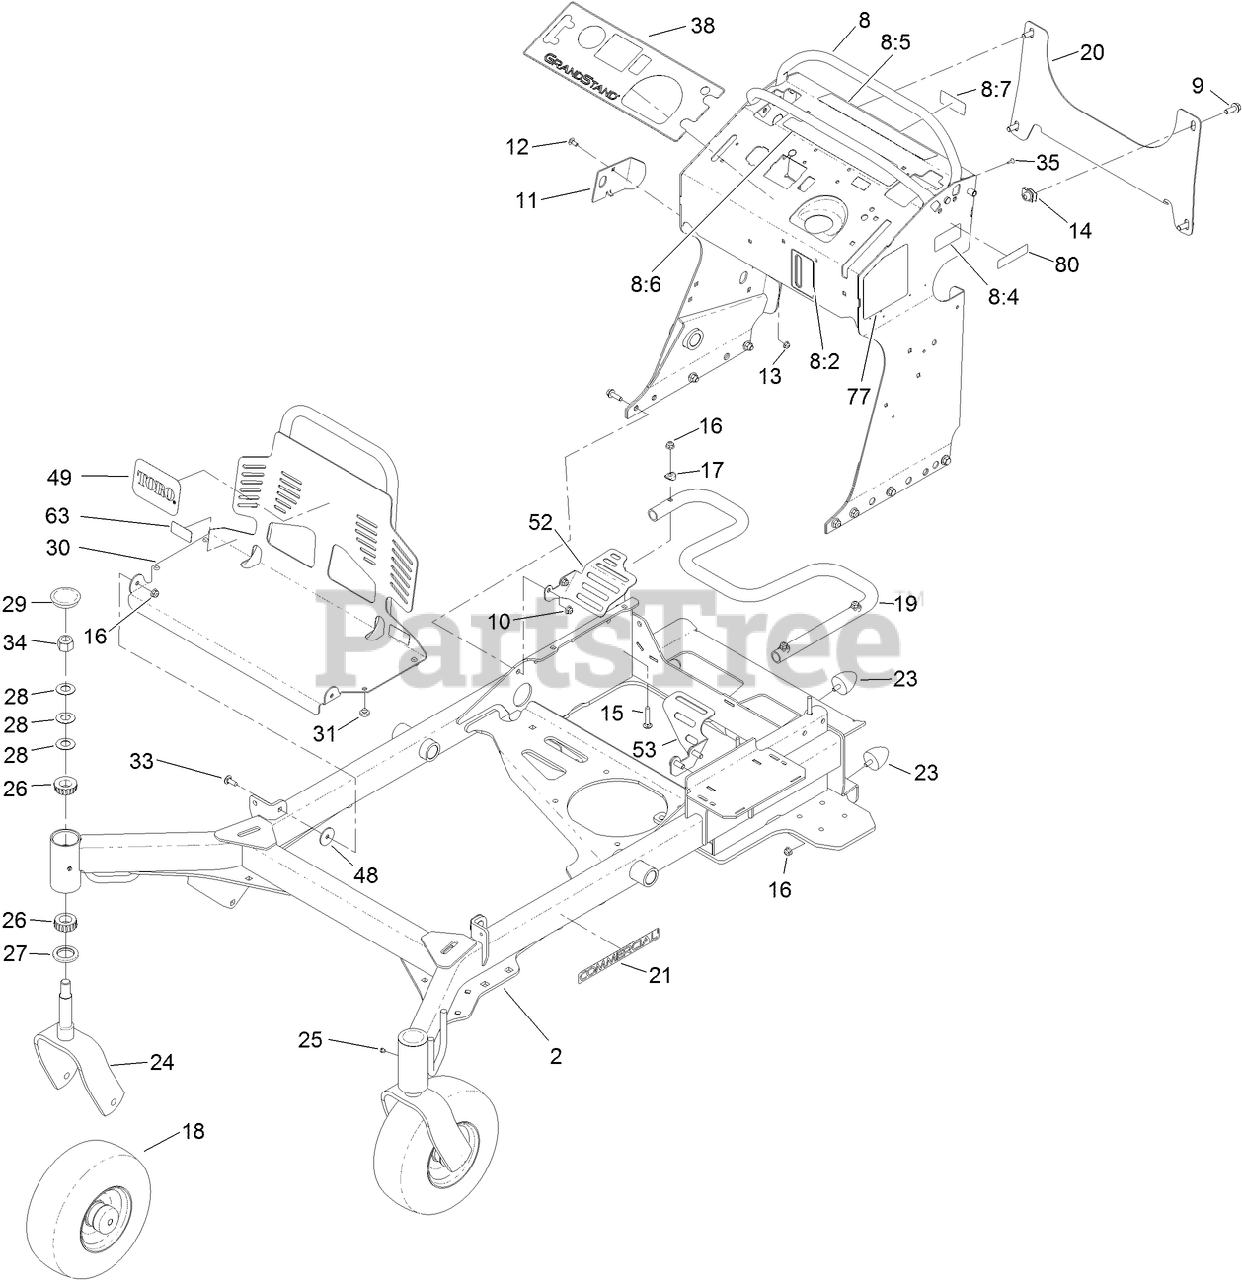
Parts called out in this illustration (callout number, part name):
8	TOWER DECAL ASM
8:2	DECAL-LEVEL, OIL
8:4	DECAL-FILL, FUEL
8:5	DECAL-WARNING
8:6	DECAL-CONTROLS
8:7	DECAL-FUSE
9	SCREW-HHF
10	NUT-HF, NI
11	PLATE-STRIKER
12	SCREW-CARR
13	NUT-HF
14	NUT-TINNERMAN
15	BOLT-CAR
16	NUT-HF, NI
17	WASHER
18	WHEEL/TIRE AND BEARING ASM
19	TUBE-MOUNT, FUEL TANK
20	BRACKET-CROSS
21	DECAL-COMMERCIAL
23	BUMPER-RUBBER
24	FORK-CASTER
26	BEARING-ROLLER, TAPERED
27	SEAL-GREASE
28	WASHER-BELLVILLE
29	CAP-GREASE
30	GUARD-ENGINE
31	BUMPER
33	BOLT-CARR
34	NUT-LOCK, NI
35	RIVET-POP
38	DECAL-PANEL, CONTROL
48	WASHER-NYLON
52	GUARD-FAN, RH
53	GUARD-FAN, LH
63	DECAL-WARNING, NO RIDERS
77	DECAL-SERVICE AID
80	DECAL-ARRESTOR, SPARK
